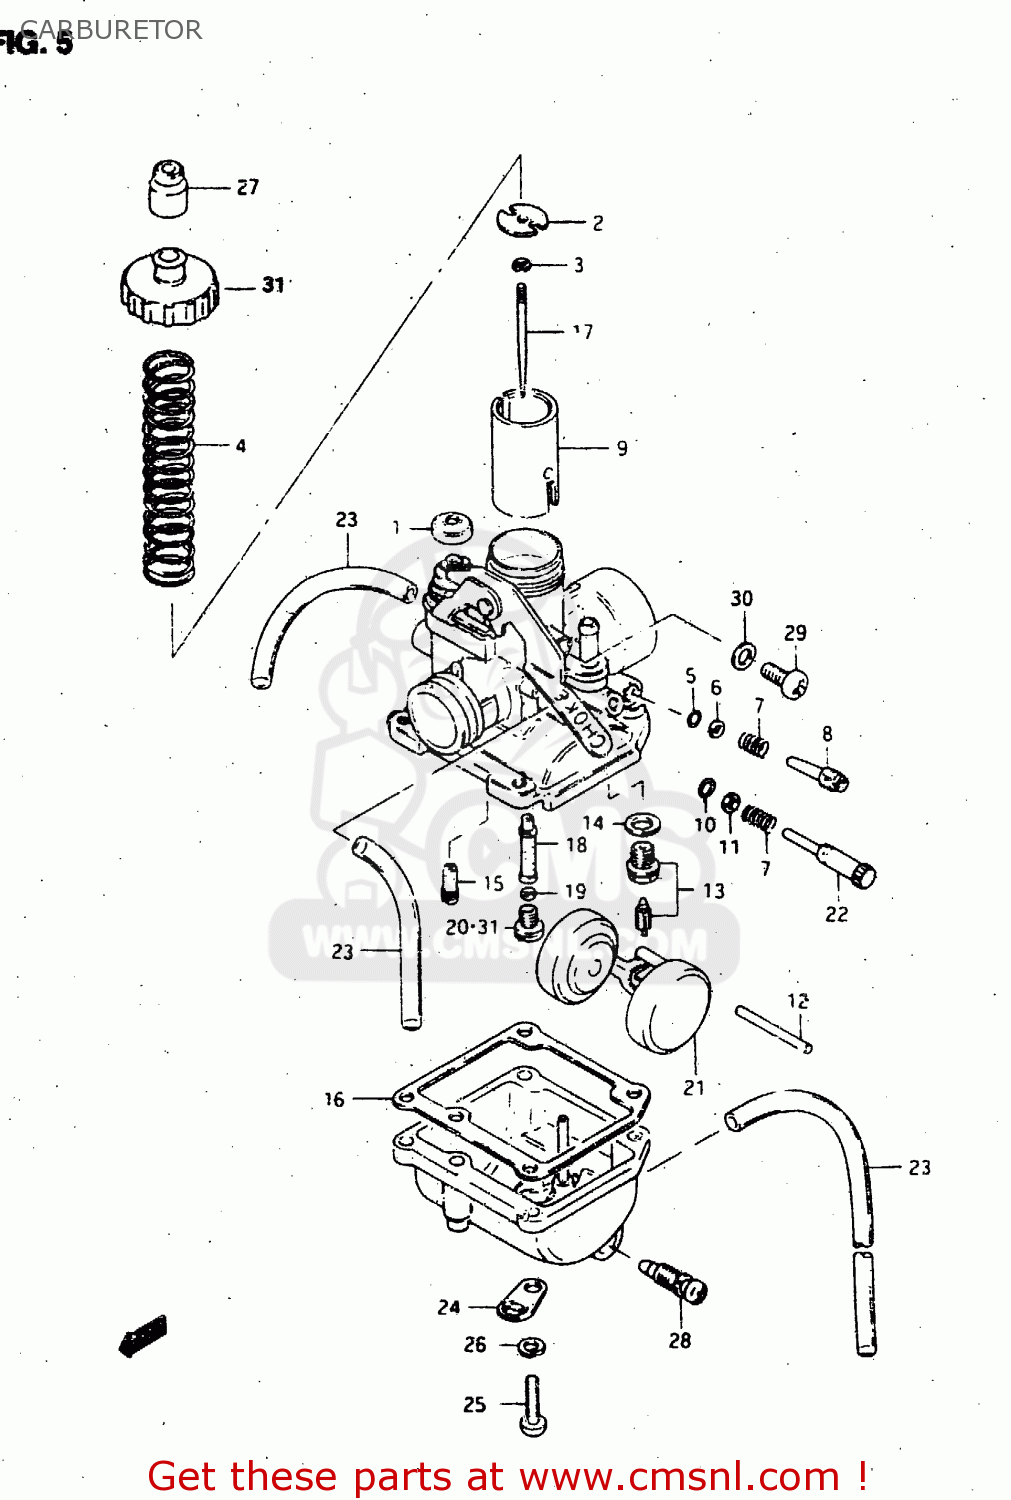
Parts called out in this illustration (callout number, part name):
1	CAP,PLUNGER
2	STOPPER,NEEDLE CLIP
3	CLIP,NEEDLE
4	SPRING,THROTTLE VALVE
5	O RING,PILOT AIR SCREW
6	WASHER
7	SPRING
8	SCREW,PILOT AIR
9	VALVE,THROTTLE(CA:2.5)
10	O RING
11	WASHER
12	PIN,FLOAT
13	VALVE ASSY,NEEDLE
14	GASKET,NEEDLE VALVE (NAS)
15	JET,PILOT 20
16	GASKET,FLOAT CHAMBER (NAS)
17	NEEDLE,JET(3CV1)
18	JET,NEEDLE
19	PACKING,MAIN JET (NAS)
20	JET,MAIN(70)
21	FLOAT
22	ADJUSTER
23	HOSE(3X5X600)
24	PLATE
25	SCREW 4X16
26	WASHER,LOCK
27	CAP
28	SCREW,DRAIN
29	SCREW
30	GASKET,DRAIN PLUG (NAS)
31	CAP
